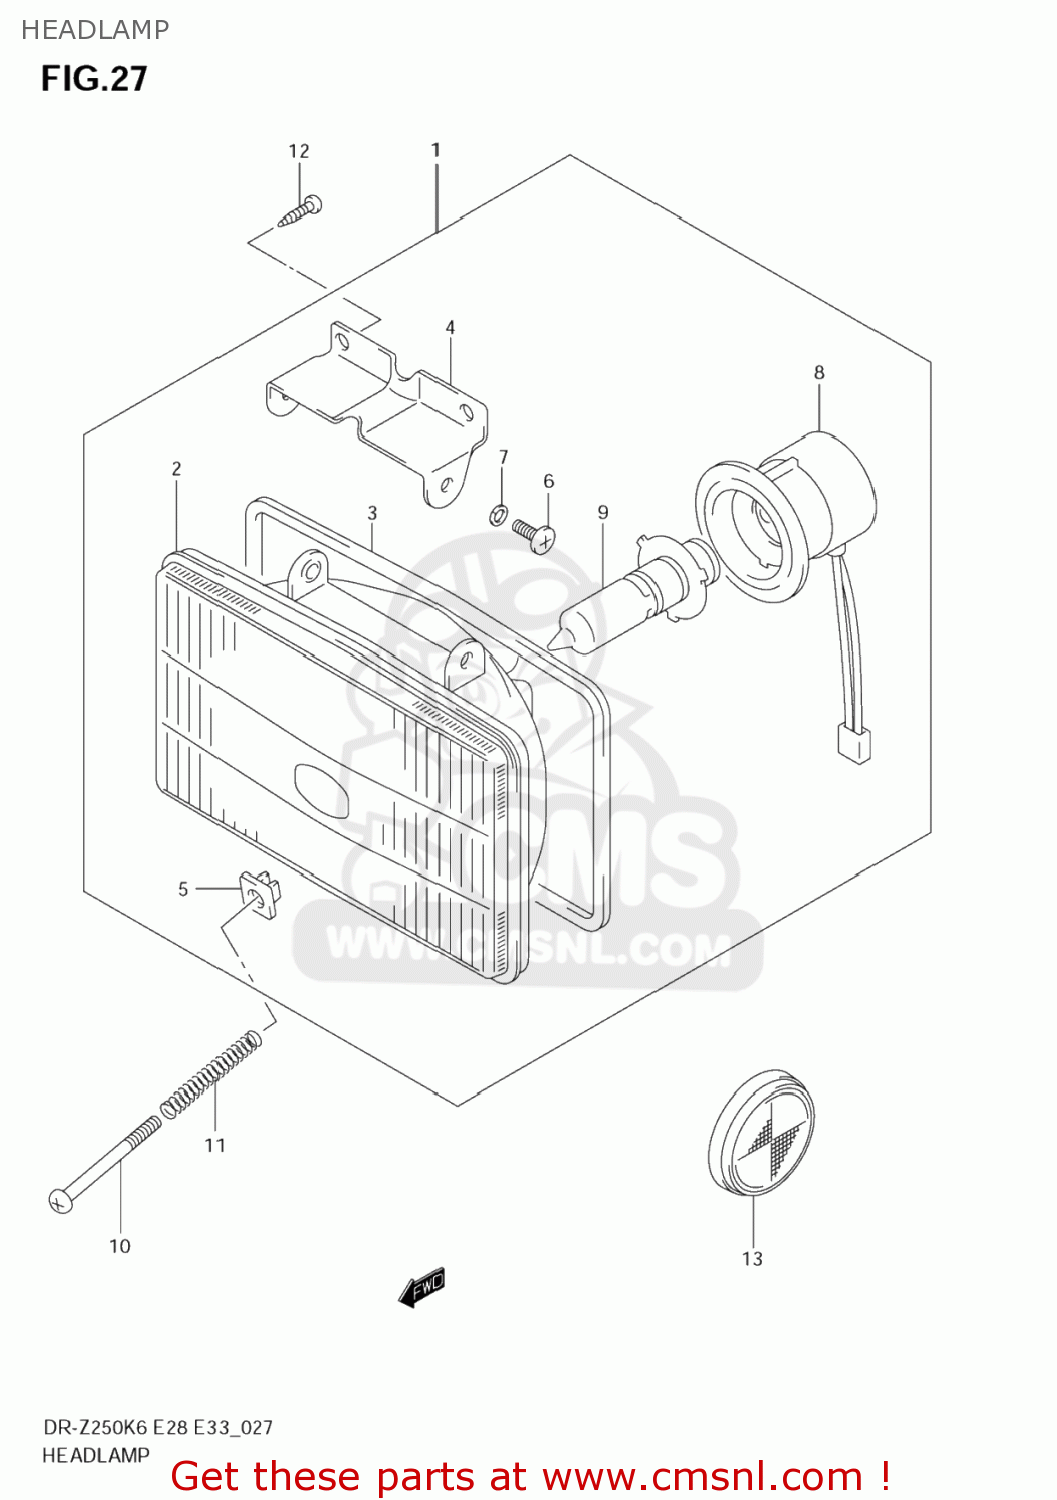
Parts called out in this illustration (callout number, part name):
1	HEADLAMP ASSY
2	UNIT,LAMP
3	GASKET,HEADLAMP (NAS)
4	BRACKET,LAMP
5	NUT,ADJUSTING
6	SCREW
7	WASHER,LOCK
8	SOCKET
9	BULB(12V35/36.5W)
10	SCREW(4X75)
11	SPRING
12	SCREW
13	REFLECTOR,REFLEX FR
